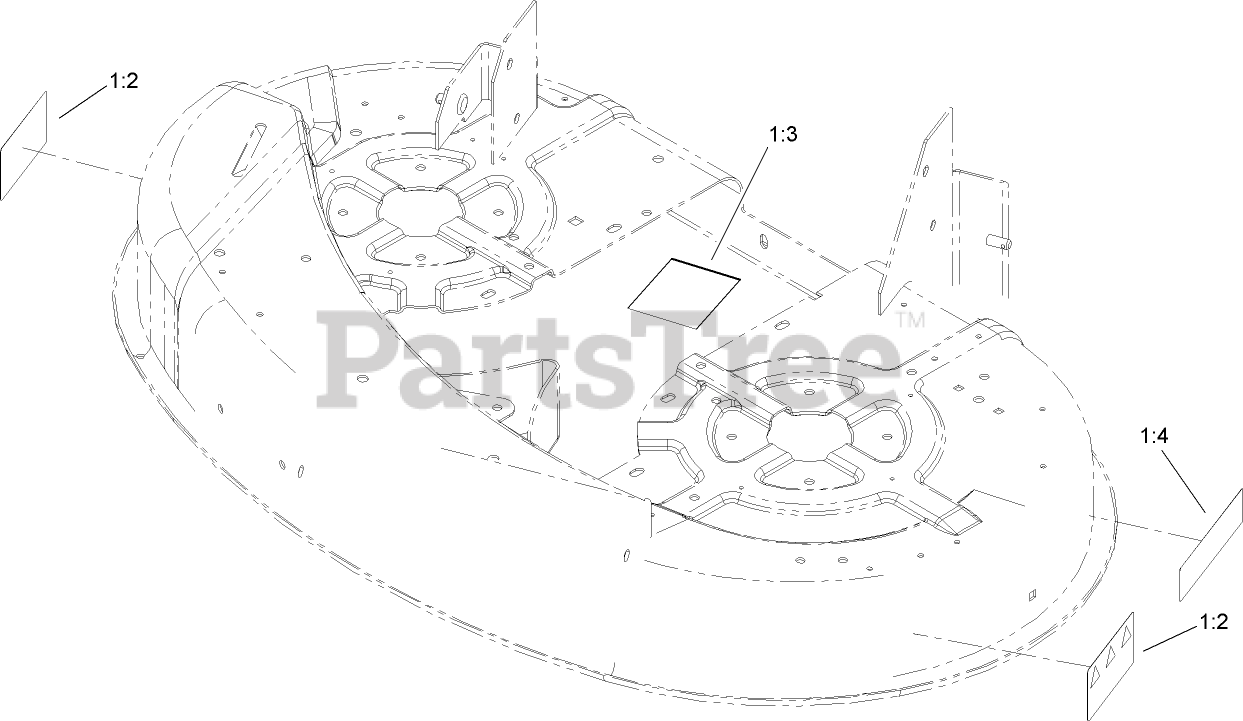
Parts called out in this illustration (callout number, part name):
1	Loose Parts Package
1:2	DECAL-DANGER
1:3	DECAL-BELT ROUTING
